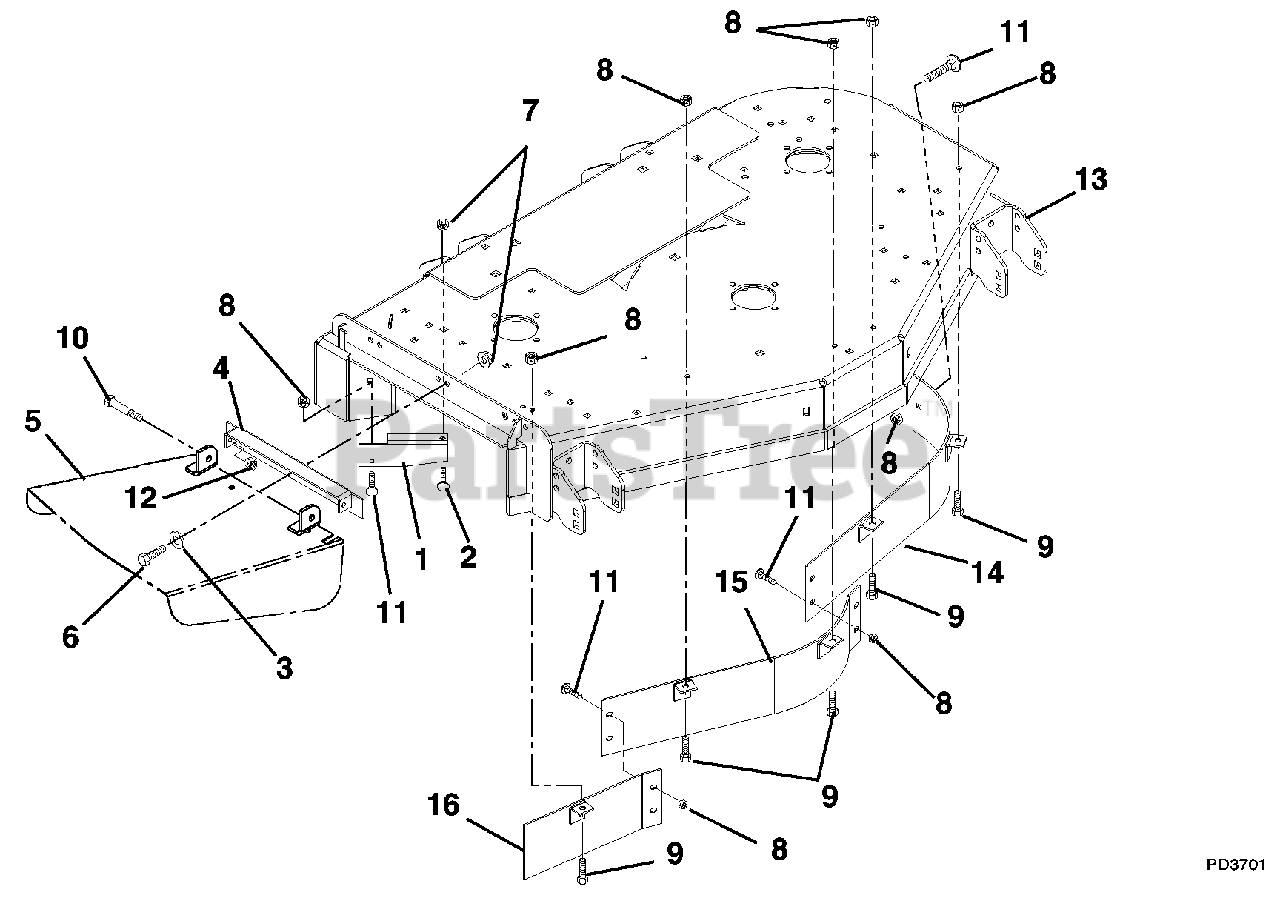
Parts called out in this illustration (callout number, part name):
1	Deflector, 52" (044, 054)
1	Deflector, 60" (051, 055)
1	Deflector (042, 043, 310, 311)
2	Bolt, Round Head Square Neck .38-16 x 1.00 Grade 5
3	Washer, Flat Steel .38 x .875 x .083 (042, 043, 044, 054, 310, 311)
4	Weldment Discharge Chute Bracket (042, 043, 044, 054, 310, 311)
4	Weldment Discharge Chute Bracket (051, 055)
5	Chute, Discharge (042, 043, 044, 054, 310, 311)
5	Chute, Discharge (051, 055)
6	Bolt, Hex .38-16 x 1.00 Grade 5
7	Nut, Locking Top Flange .38-16
8	Nut, Locking Top Flange .31-18
9	Bolt, Hex .31-18 x .75 Grade 5
10	Bolt, Shoulder .38-16 x .50 Socket Head
11	Bolt, Round Head Square Neck .31-18 x .75 Grade 5
12	Nut, Locking Center .38-16
13	Weldment, 52" Mower Deck (044, 054)
13	Weldment, 60" Mower Deck (051, 055)
13	Weldment, 44" Mower Deck Float (042, 310)
13	Weldment, 48" Mower Deck (043, 311)
14	Weldment, Upper Baffle Left - 52" (044, 054)
14	Weldment, Upper Baffle Left - 60" (051, 055)
14	Weldment, Baffle Left Front - 44" (042, 310)
14	Weldment, Upper Baffle Left - 48" (043, 311)
15	Weldment, Baffle Center Front - 52" (044, 054)
15	Weldment, Baffle Center Front - 60" (051, 055)
15	Weldment, Baffle Center Front - 44" (042, 310)
15	Weldment, Upper Baffle Center-48"(043, 311)
16	Weldment, Baffle Right Front - 52" (044, 054)
16	Weldment, Baffle Right Front - 60" (051, 055)
16	Weldment, Baffle Right Front - 44" (042, 310)
16	Weldment, Upper Baffle Right - 48"(043, 311)
